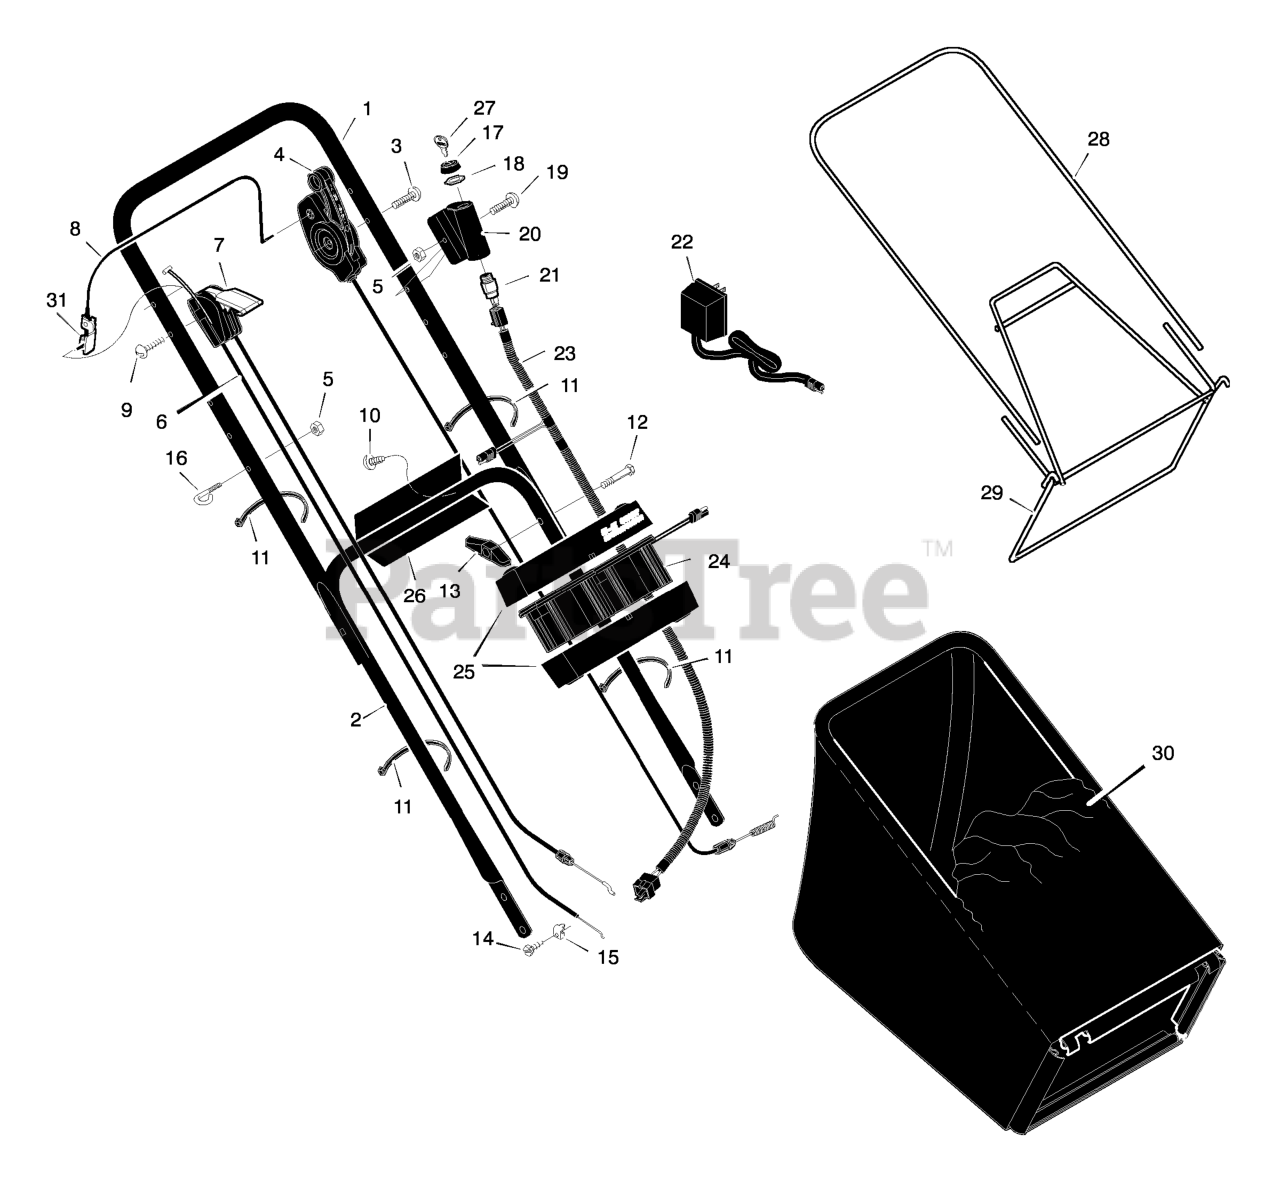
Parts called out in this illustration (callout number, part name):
1	Handle, Upper
2	Handle, Lower
4	Control, Drive
5	Locknut
6	Cable, Stop
7	Throttle Control
8	Engine Stop Lever
11	Fastener, Cable
13	Knob
16	GUIDE, ROPE
17	Cap
18	Nut
20	Cover, Ignition
21	Switch Ignition & Key
22	Charger, Battery
23	Harness, Wiring
24	Battery
25	Case, Battery
26	Bracket, Battery
27	Key, Ignition
28	Frame, Top
29	Frame Assembly
30	Bag, Cloth
31	Bracket, Stop Lever
